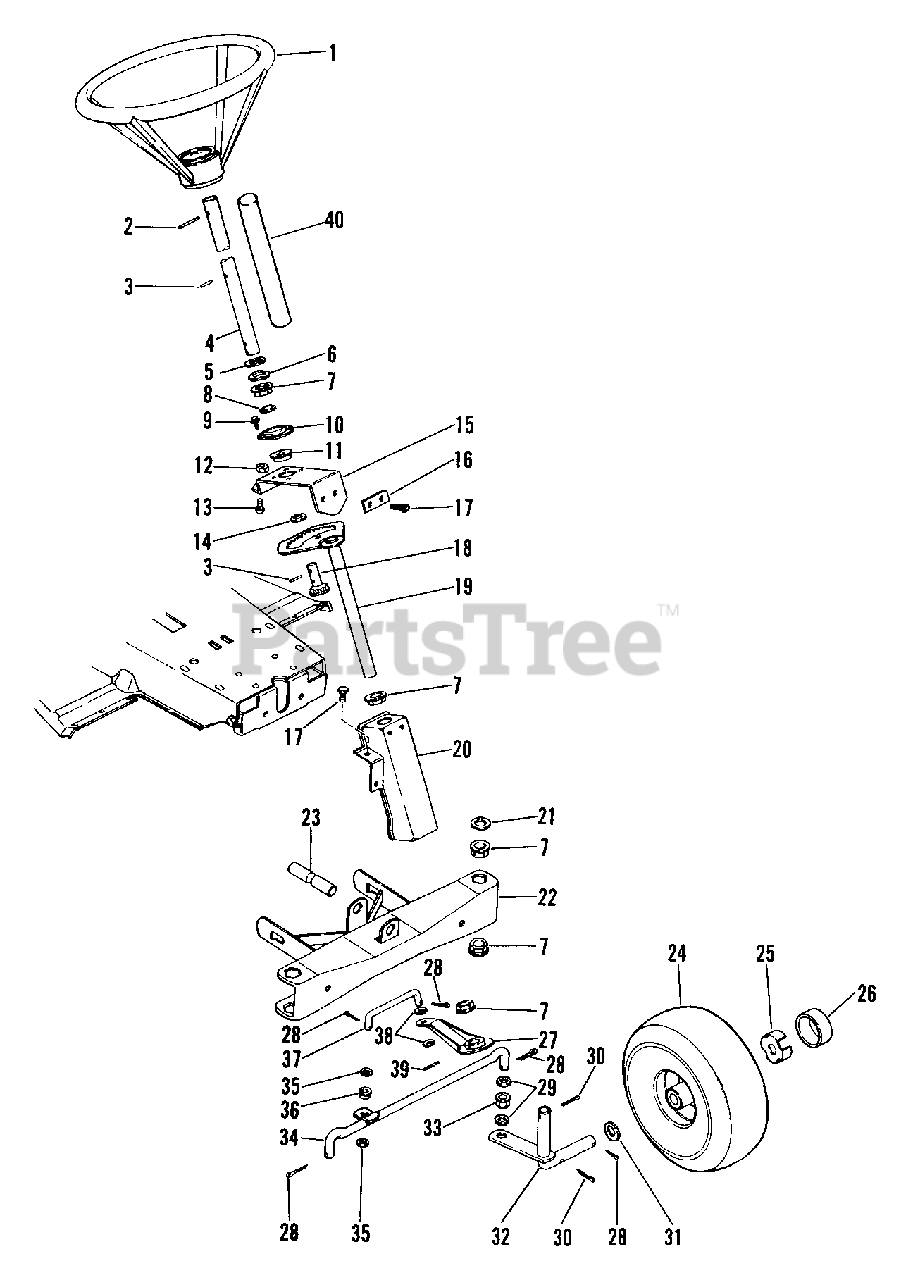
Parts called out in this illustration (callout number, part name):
1	STEERING WHEEL
2	PIN-ROLL .250X1.75
3	PIN-ROLL .188X1.00
4	STEERING SHAFT
5	WSHR-FL-STL .755X1.375X.062 PL
6	SPRING WASHER
7	FLANGE BUSHING
8	PUSH NUT, .50
9	SCR-TAP 10-24X.25 CRSLPH PL 1A
10	RETAINING PLATE
11	BSHG-FLG .625X1.156X.375 SI
12	NUT-LK .312-18 GR A PL
13	BLT-RDHDSQSHNK .31-18X.50 YZ
14	WSHR-FL-STL .630X1.005X.062 PL
15	STEERING SUPPORT
17	SCR-TAP .312-18X.75 HWH PL TR
18	STEERING PINION
19	STEERING GEAR
20	DEEP DRAW STEERING BOXES
21	WSHR-FL-STL .755X1.375X.062 PL
22	FRONT AXLE
23	AXLE PIVOT PIN
24	T/WHL ASSY FRT
24	TIRE 4.10/3.50-4
24	T/WHL ASSY
24	WHL
24	WHL-COMP
24	BSHG-FLG .750X1.380X.750X1.557
24	ZERK FITTING
25	SPINDLE CUP
26	HUB CAP
27	STEERING ARM
28	PIN-COTR .12X1.0 PL
29	WSHR-FL-STL .505X.875X.024 PL
30	PIN-COTR .12 X 1.25 PL
31	SPINDLE WASHER
32	RH WHEEL SPINDLE
32	L.H. WHEEL SPINDLE
33	BSHG-FLG.500X.625X.312X.750NY
34	TIE ROD
35	WSHR-FL-STL .380X.626X.033
36	BSHG-FLG .372X.500X.312X.625NY
37	STEERING LINK
38	WSHR-FL-STL .406X.865X.094 PL
39	PIN-GRV .188X1.25 TP A
